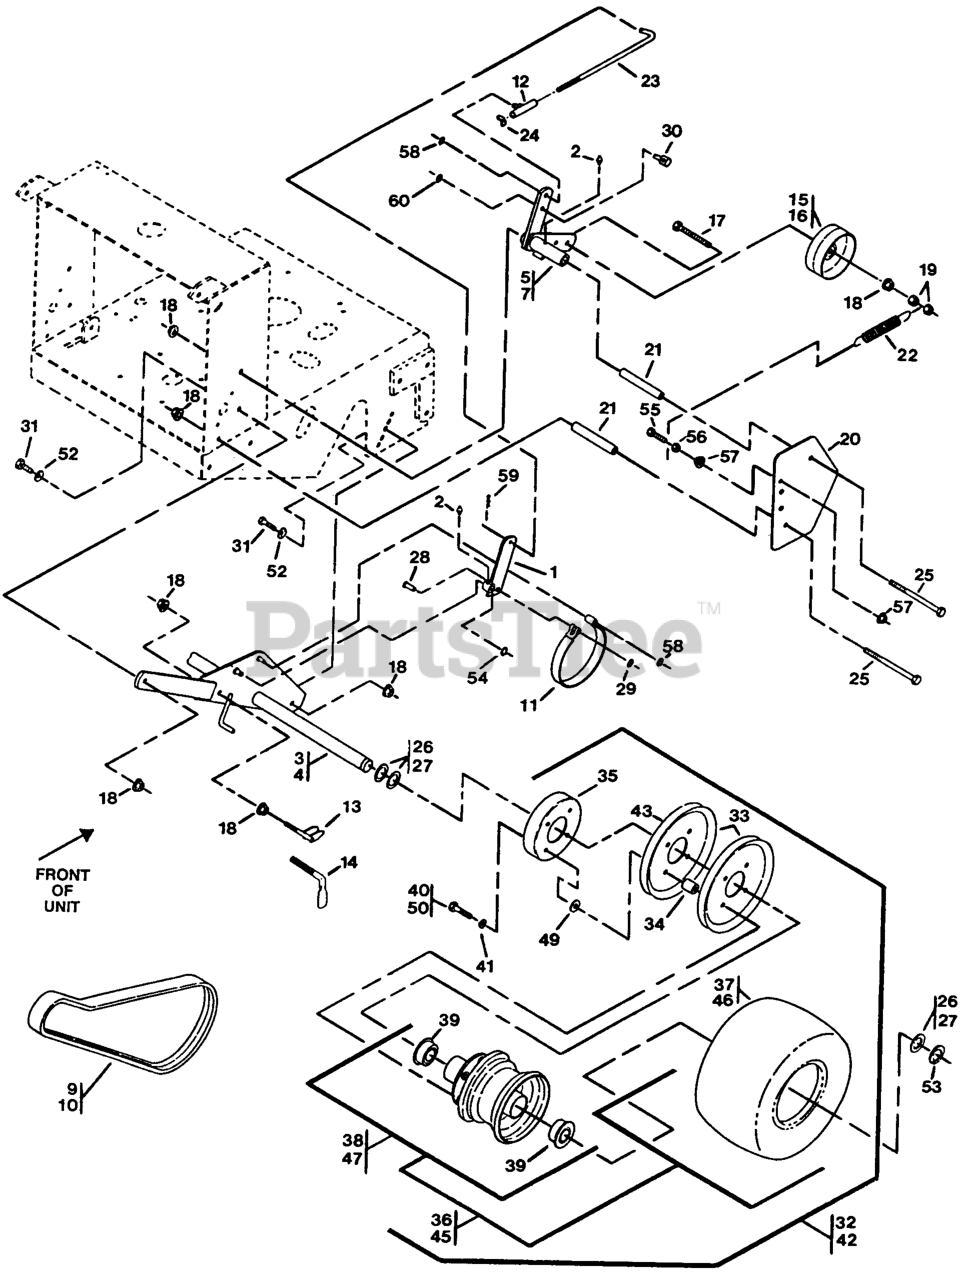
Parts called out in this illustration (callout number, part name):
9	BELT,WHEEL DRIVE
10	BELT-WHEEL, DRIVE
11	BAND-BRAKE
14	SCRAPER
15	IDLER-WHEEL, DRIVE
16	IDLER-WHEEL, DRIVE
20	SHIELD-WHEEL, DRIVE
21	SPACER-SHIELD
22	SPRING-EXTENSION
23	ROD-BRAKE
24	WINGNUT-NYLOCK
26	WASHER-SPACER
28	PIN-CLEVIS
29	RING-RETAIN,PUSH,EXT,FLAT
30	SWIVEL-SHORT, ADJUSTABLE
33	SHEAVE-WHEEL, DRIVE
34	WHEEL AND HUB ASM
35	DRUM-BRAKE
38	WHEEL AND HUB ASM
39	BEARING-FLANGED
41	WASHER-LOCK
42	DRIVE WHEEL ASM
43	SHEAVE-WHEEL, DRIVE
45	WHEEL AND TIRE ASM
47	WHEEL AND HUB ASM
53	RING-SNAP
59	PIN-COTTER
